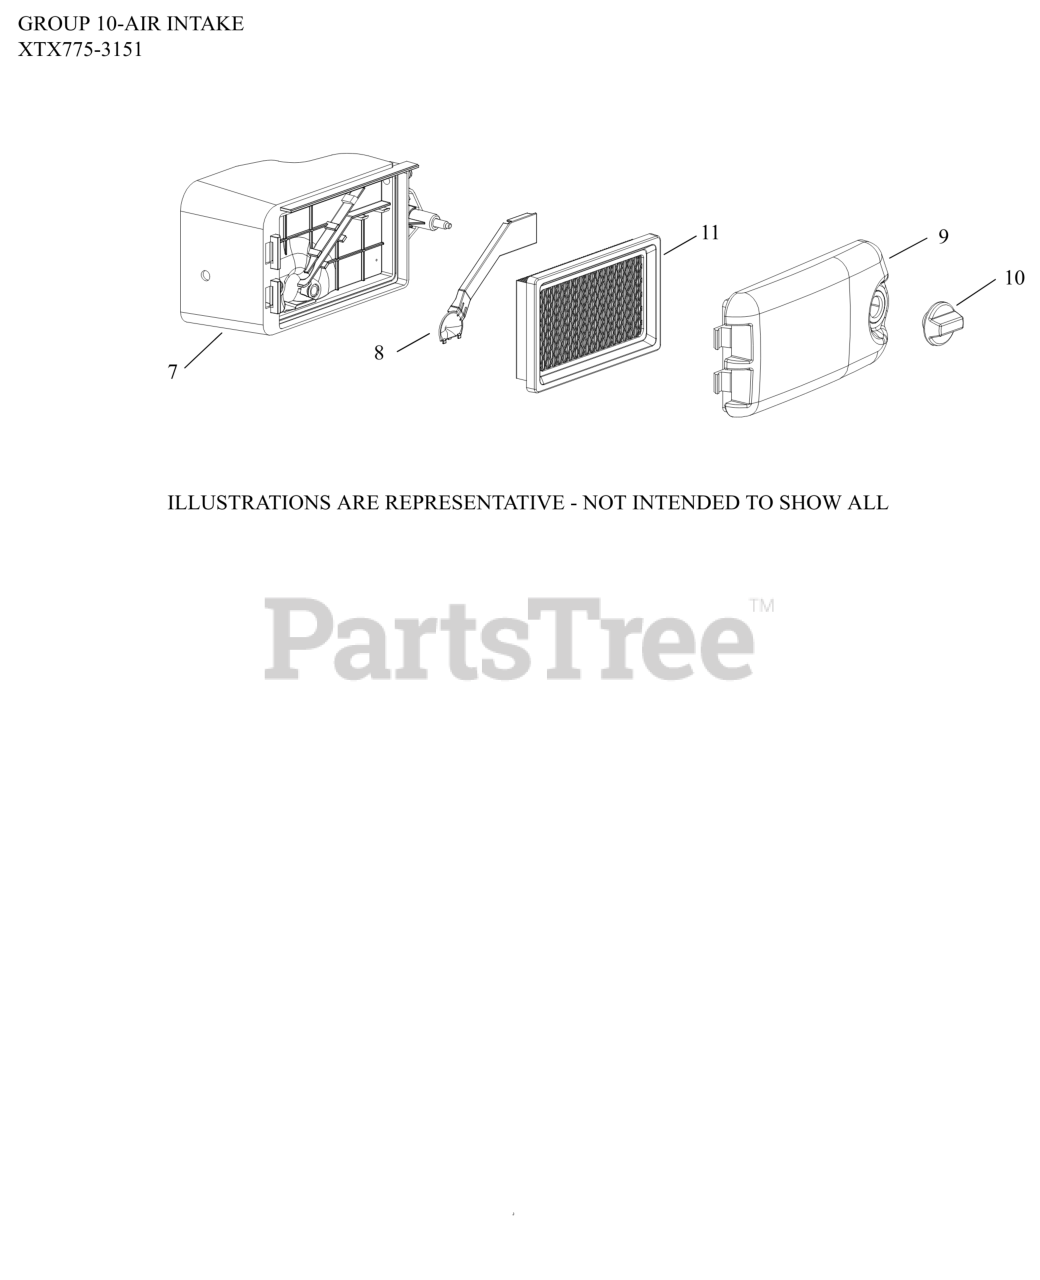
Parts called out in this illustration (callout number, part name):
7	AIR CLEANER BASE-USE 14 094 23-S
8	COVER, A/C BASE (BREATHER GAS)
9	COVER, AIR CLEANER
10	KNOB-USE 14 341 07-S
11	ELEMENT, AIR FILTER
